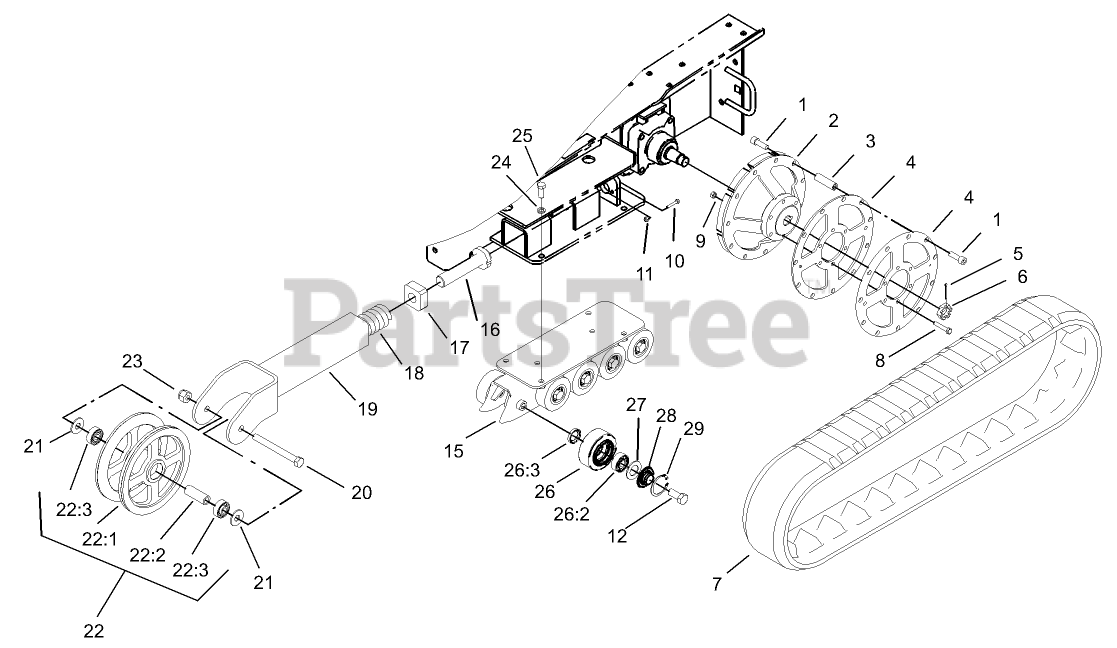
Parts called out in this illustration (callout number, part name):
1	SCREW-HSH
2	Drive Wheel ASM
3	SPACER-WHEEL, DRIVE
4	PLATE-WHEEL, DRIVE
5	PIN-COTTER
7	TRACK
8	SCREW-HH
9	NUT-LOCK, SIDE
10	SCREW-HH
11	NUT-LOCK, NI
12	SCREW-HH
15	TRACK GUIDE ASM
16	BOLT-TENSIONER
17	BLOCK-TENSIONER
18	SPRING-COMPRESSION
19	TENSIONER ARM ASM
20	SCREW-HH
21	WASHER-FLAT
22	TENSIONER WHEEL ASM
22:1	WHEEL-TENSIONER
22:2	SPACER-WHEEL, TENSIONER
22:3	BEARING
23	NUT-HEX
24	WASHER-LOCK
25	SCREW-HH
26	Road Wheel ASM
26:2	BEARING
26:3	SEAL-OIL
27	Gasket-Bogie
28	CAP-WHEEL, BEARING
29	RING-SNAP, INTERNAL
